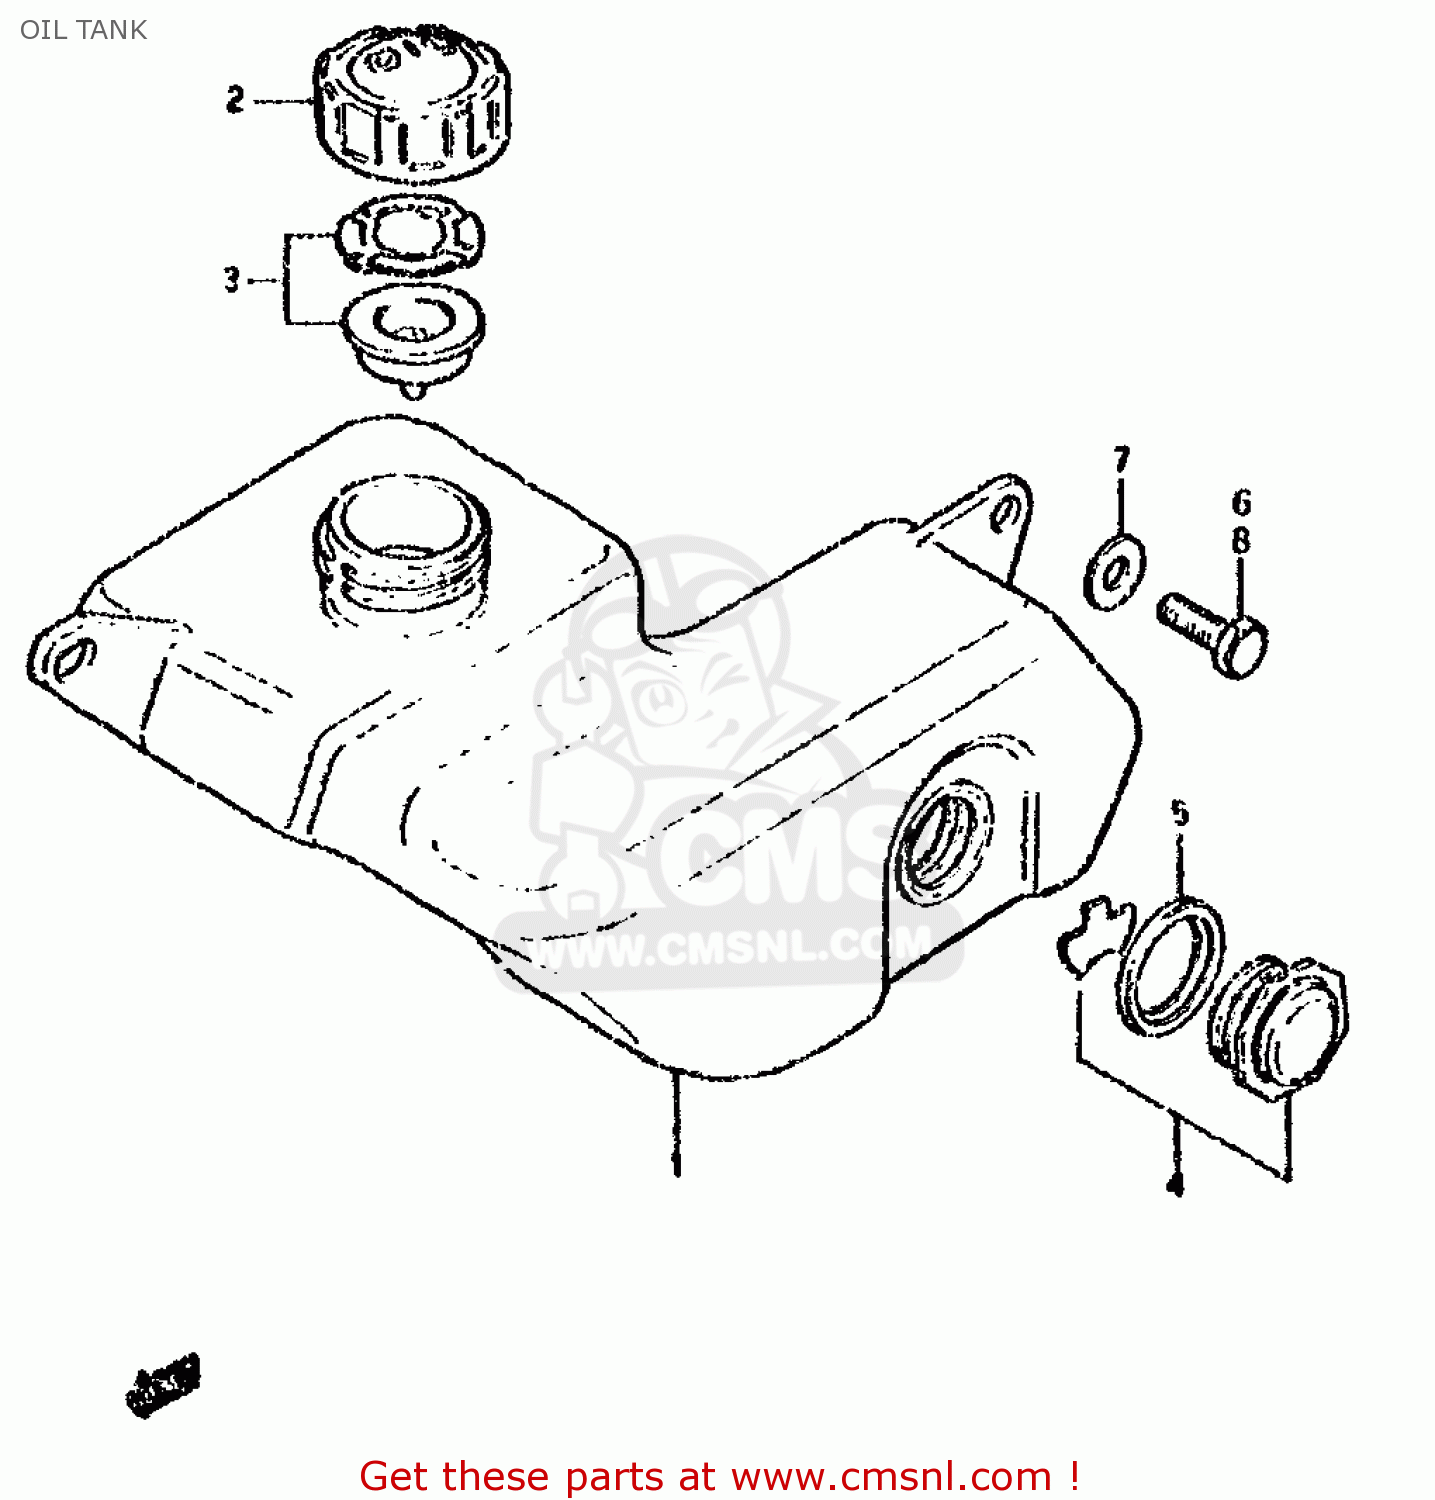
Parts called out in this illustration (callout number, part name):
1	TANK,OIL
2	CAP,OIL TANK
3	GASKET SET (NAS)
4	LENS SET,OIL LEVEL
5	GASKET (NAS)
6	BOLT
7	WASHER
8	BOLT(6X16)
